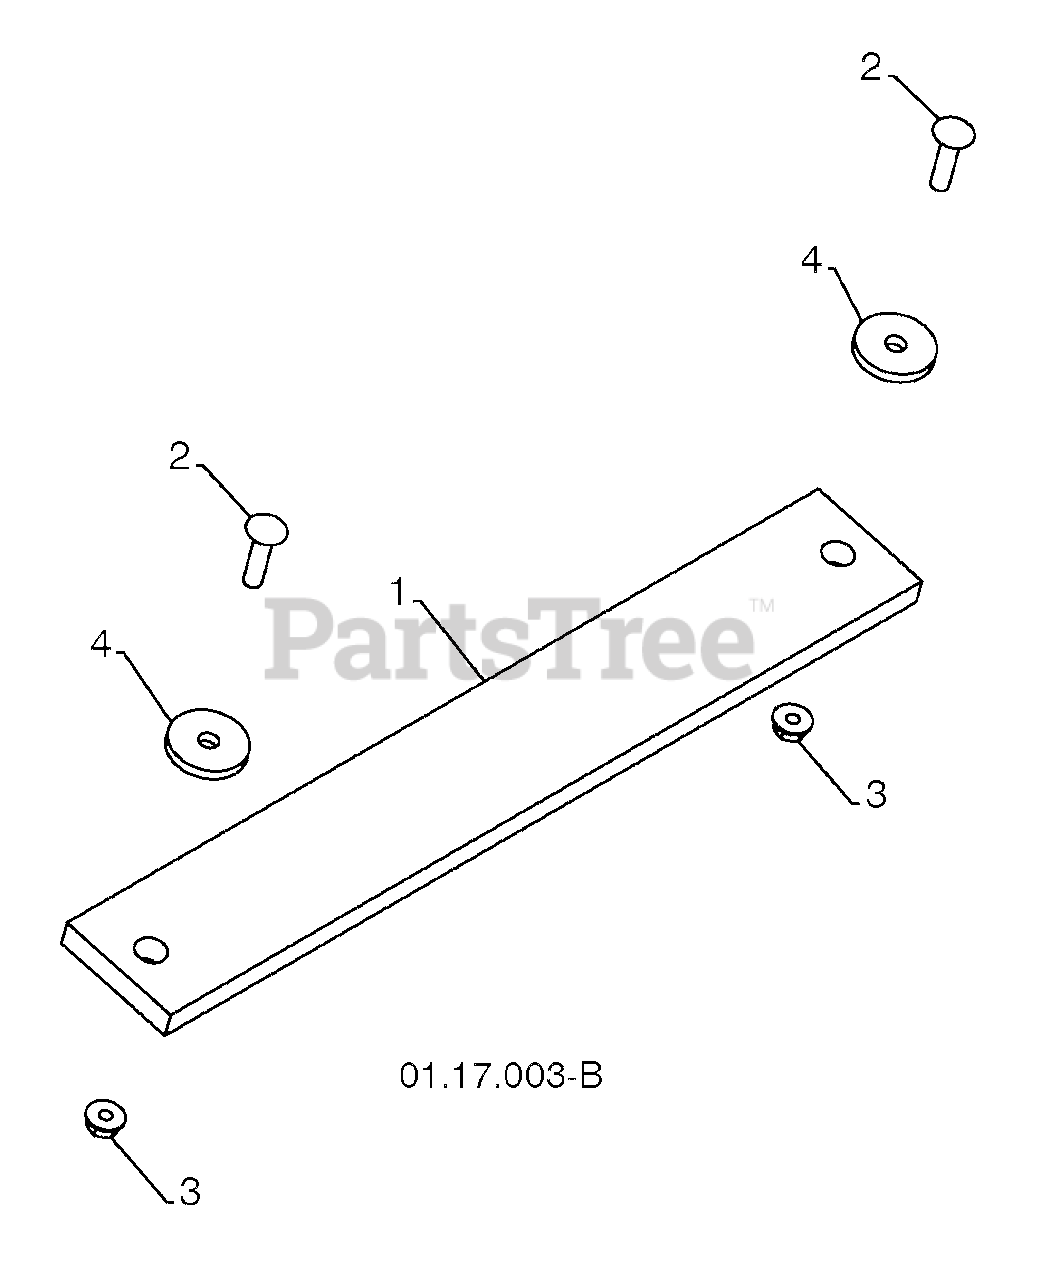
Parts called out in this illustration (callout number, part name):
1	WEIGHT BAR
2	CARRIAGE BOLT 5/16-18 X 1.25
3	NUT 5/16-18
4	WASHER
